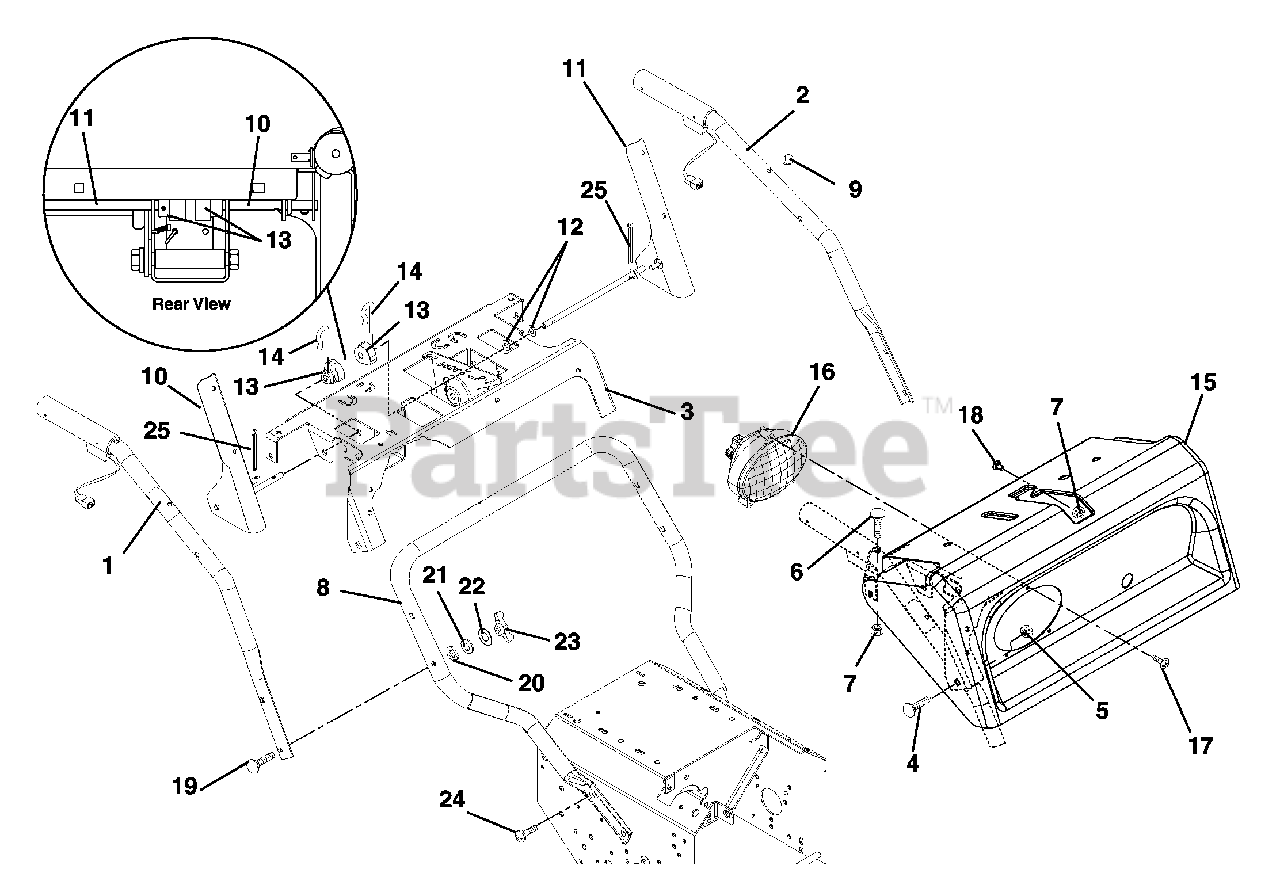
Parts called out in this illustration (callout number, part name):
1	Handlebar, Upper Right Hand
2	Handlebar, Upper Left Hand
3	Panel, Sub Weldment
4	Bolt, Round Head Square Neck .31-18 x 1.50 Grade 5
5	Nut, Locking Center .31-18
6	Bolt, Round Head Square Neck .25-20 x 1.25
7	Nut, Locking Center .25-20
8	Handlebar, Lower
10	Kit, Right Hand Lever with Grip
11	Kit, Left Hand Lever with Grip
12	Washer, Flat Steel .34 x .69 x .065
13	Cam, Interlock
14	Pin, Spring Clip
15	Panel with Control Decal, Gravely 936
16	Headlamp, Oval with 1156 Bulb
17	Screw, Tapping 10-16 x .75 Hi-Lo
18	Bolt, Round Head Square Short Neck.25-20 x .50
19	Bolt, Round Head Square Neck .31-18 x 2.25
20	Washer, Saddle .32 x .94 x .062
21	Washer, Locking .31 x .097 Heavy
22	Washer, Flat Steel .33 x .88 x .062
23	Knob, Wing .31-18
24	Bolt, Screw Hex Flanged Whiz Lock Head .38-16 x .75
25	Pin, Cotter .09 x .75 Extended Prong Square Cut
